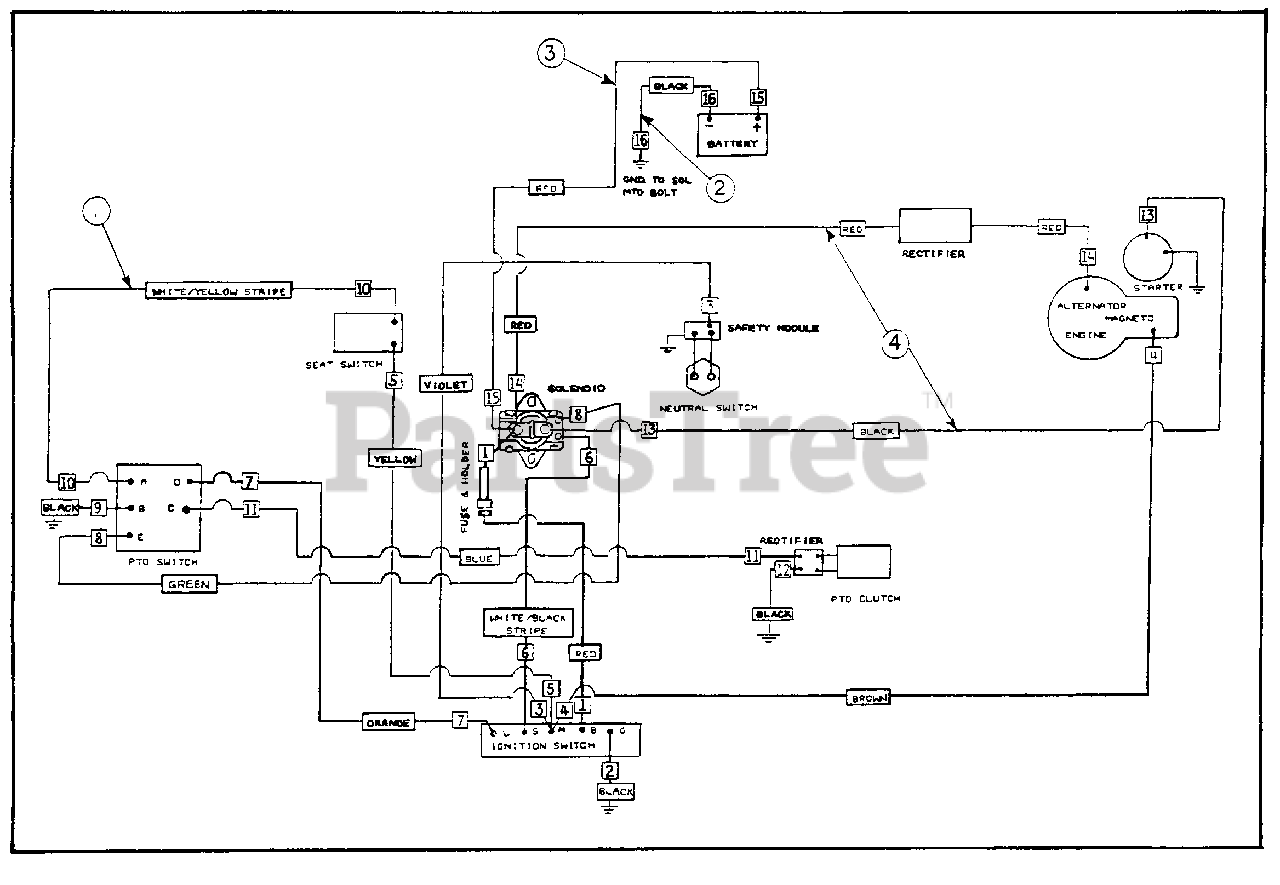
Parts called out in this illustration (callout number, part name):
1	WIRE HARNESS
2	BATTERY CABLE- Ground
3	BATTERY CABLE
4	HARNESS- Starter-Alternator
